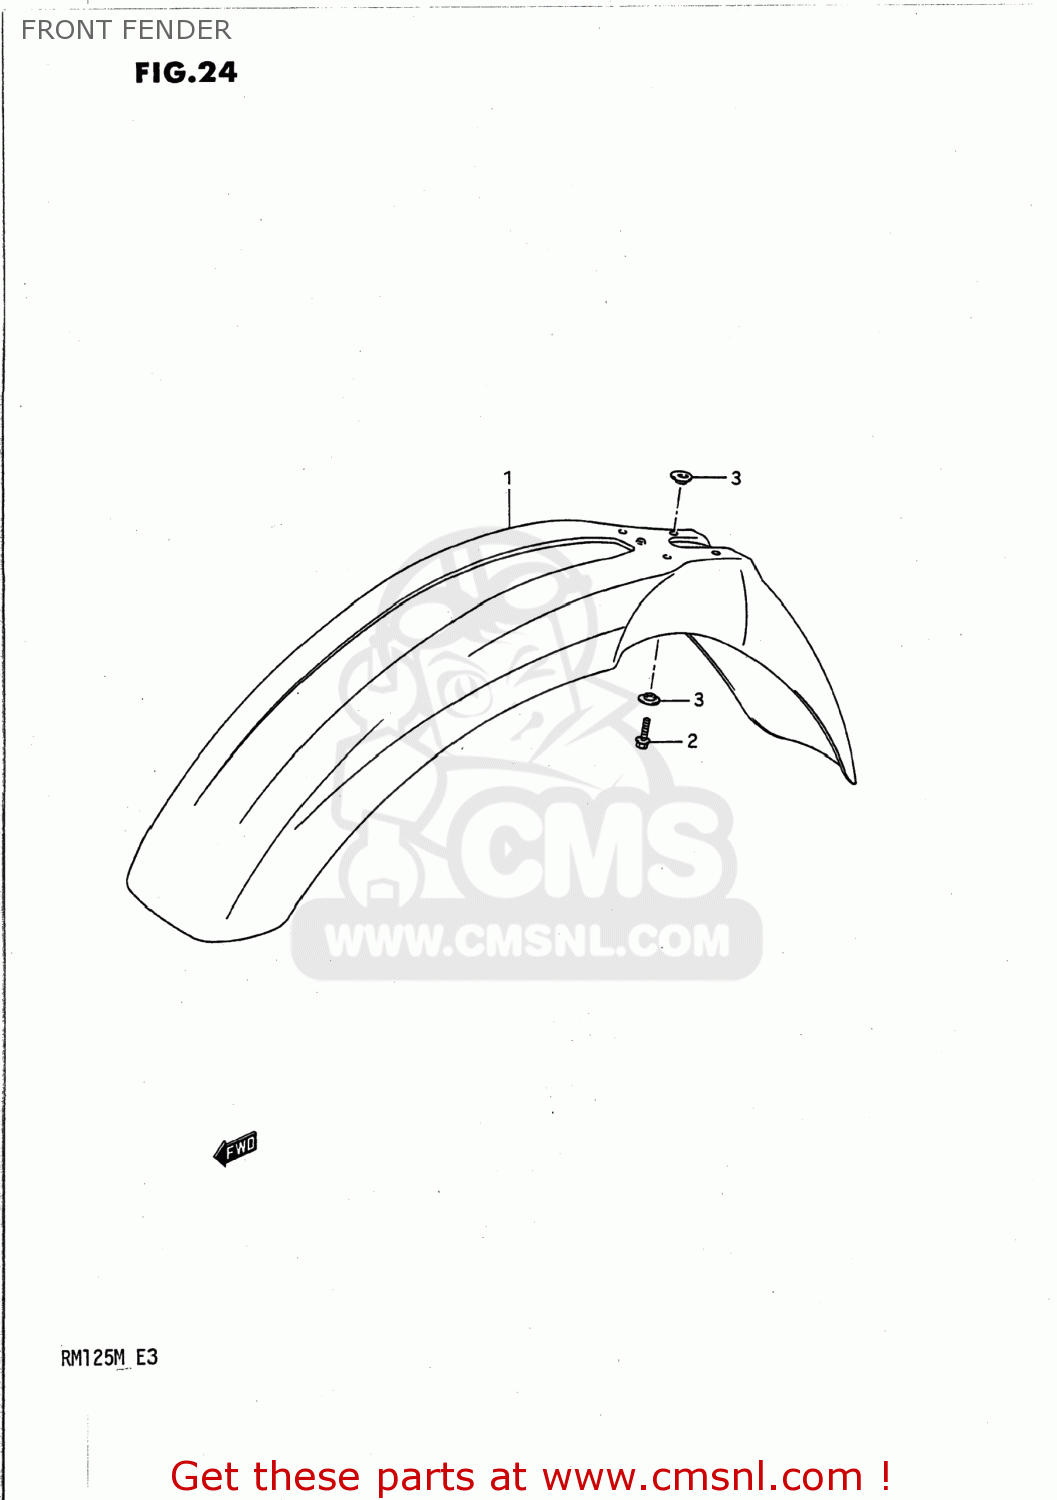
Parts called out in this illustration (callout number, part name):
1	FENDER,FRONT
2	BOLT
3	WASHER
